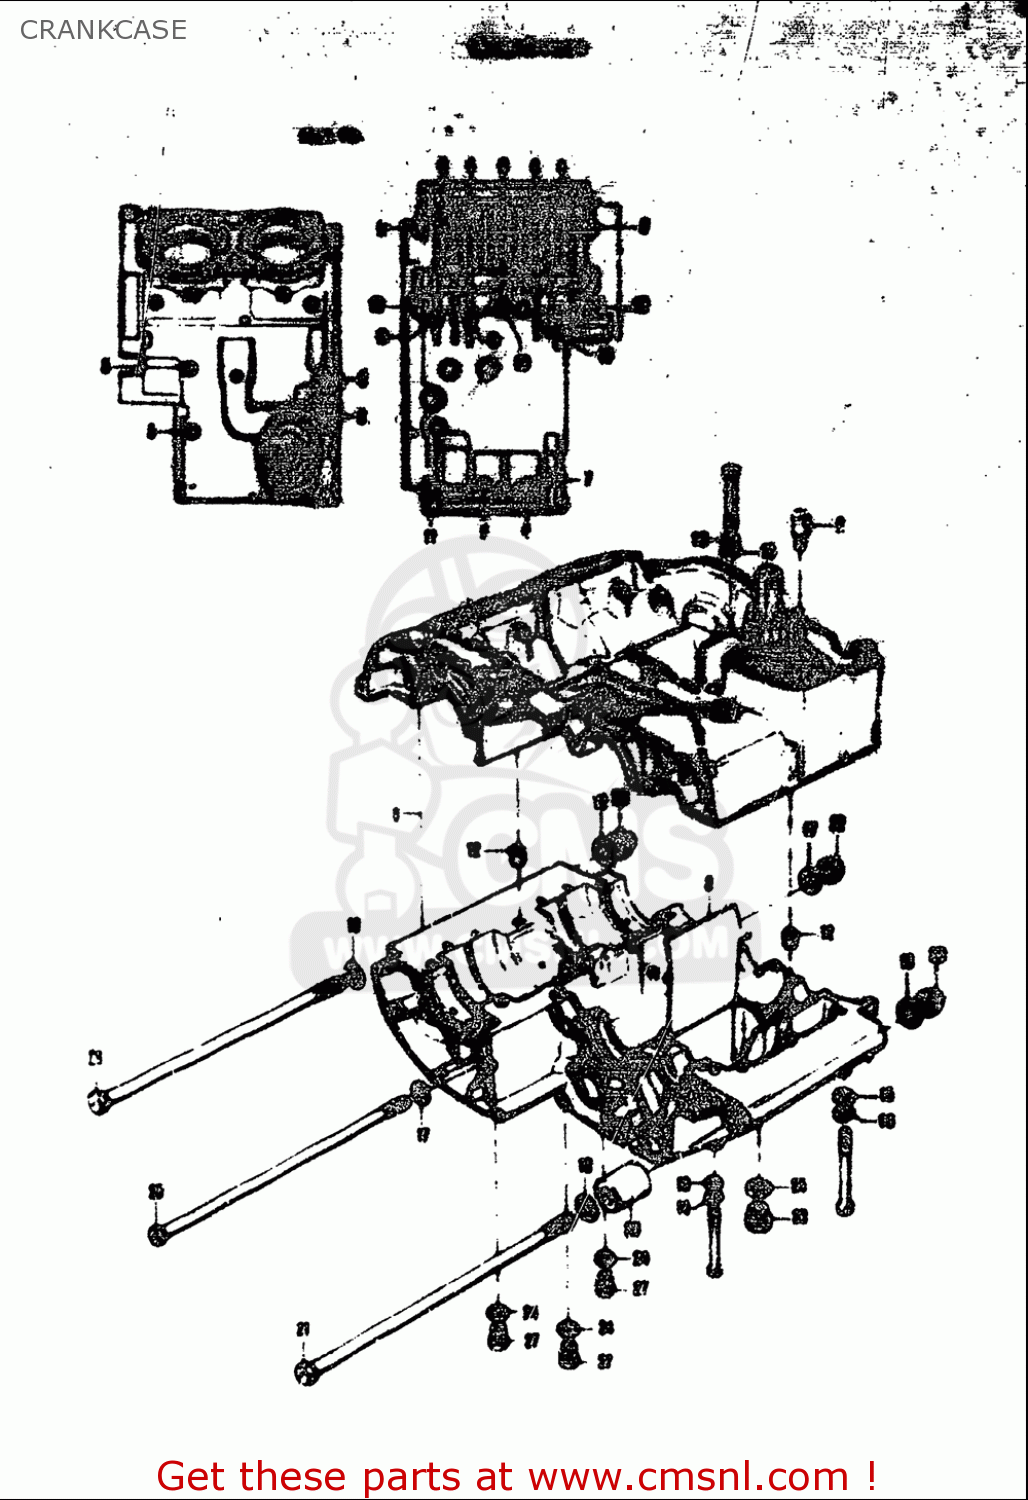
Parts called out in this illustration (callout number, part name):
4	BOLT
7	BOLT
9	BOLT
10	BOLT
11	BOLT
12	PIN
13	WASHER,LOCK
14	WASHER,LOCK
15	WASHER
16	WASHER
17	WASHER
18	WASHER
19	BOLT 8X100
23	NUT
24	GASKET(10X14X3.6) (NAS)
25	GASKET(14X19.2X2) (NAS)
26	SPACER
27	PLUG
